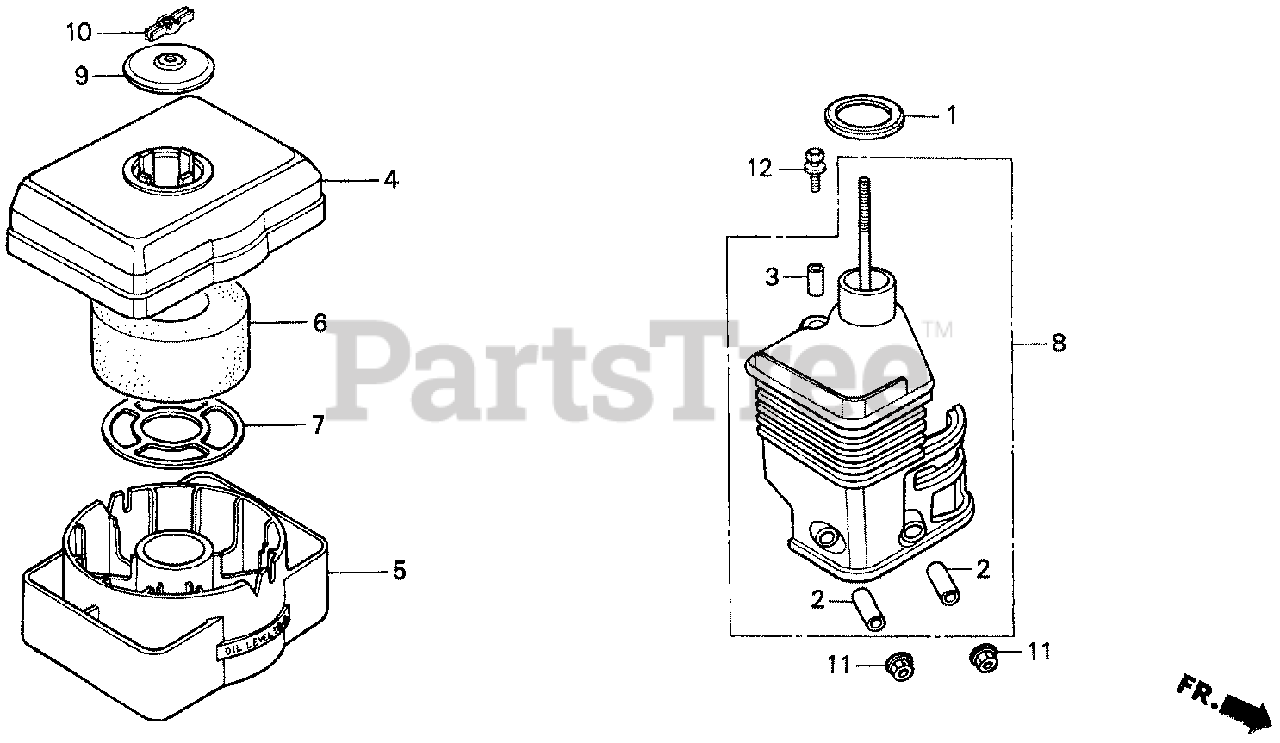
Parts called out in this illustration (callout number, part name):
1	GASKET, ELBOW
2	COLLAR, AIR CLEANER
3	COLLAR B, AIR CLEANER
4	BODY, CLEANER (OIL BATH)
5	PAN, CLEANER OIL (OIL BATH)
6	ELEMENT, AIR CLEANER (OIL BATH)
7	GRID, AIR CLEANER
8	ELBOW, AIR CLEANER
9	CAP, CLEANER
10	WINGNUT, TOOL BOX SETTING
11	NUT, FLANGE (6MM)
12	BOLT, FLANGE (6X20)
